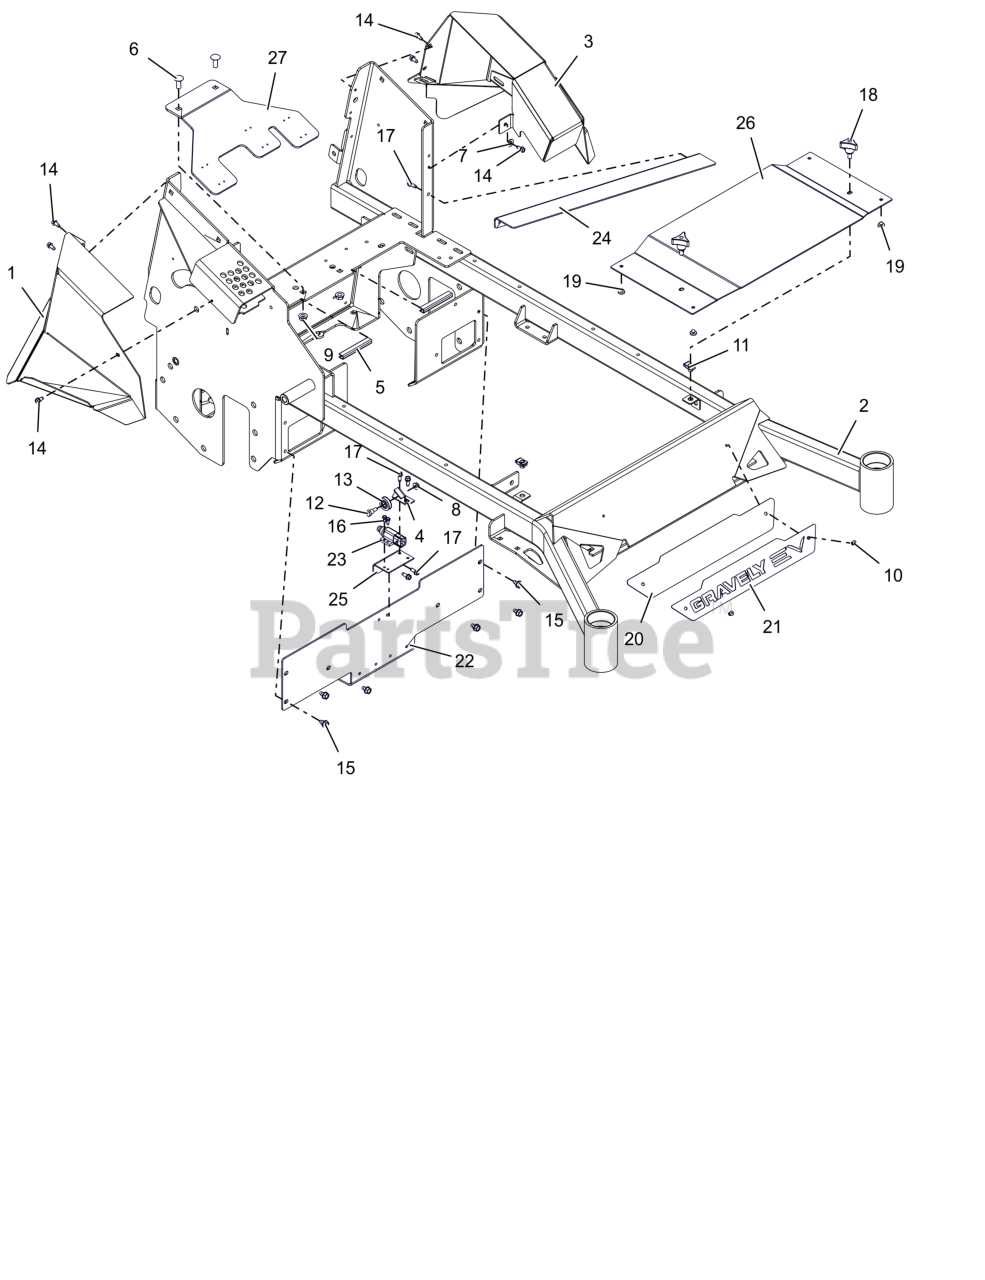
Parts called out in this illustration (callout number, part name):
1	WLDMT- RH FENDER
2	WLDMT- PROSTANCE MAIN FRAME
3	WLDMT- LH FENDER
4	BRKT, CABLE PULLEY
5	STRIP, COWL
6	BLT,RHSSN .38-16X1.00 G5 ZCC
7	WSHR,FLT .344X.688X.065 ZCC
8	NUT-LK-CTR-FLG .25-20 ZC120
9	NUT-LK-CTR-FLG .375-16 GF ZCC
10	RVT, POP .187x.250 MULTIGRIP AL
11	NUT-CLIP RETAINER 5/16-18X.56
12	BLT,SHLDR.375X.375X.25-20ZC120
13	PULLEY, CABLE
14	SCR-TAP .25-20X.50 HWH ZCC
15	SCR,TAP .312-18X.50 HWH TR ZCC
16	SCR,TAP #10-24X.50 HWH TR ZCC
17	SCR,TAP .25-20X.625 HWH ZCC
18	KNOB,WING STUD 5/16-18 X .75
19	BUMPER GROMMET
20	PLATE, BACK - GRAVELY (BLACK)
21	PLATE, LOGO - GRAVELY EV (RED)
22	PLATE- FRONT FRAME
23	SWITCH, SEALED PLUNGER
24	BRKT, DRIP EDGE (BLACK)
25	BRKT- LOWER BRAKE RELEASE
27	BRKT, ANDERSON MTG (RED)
